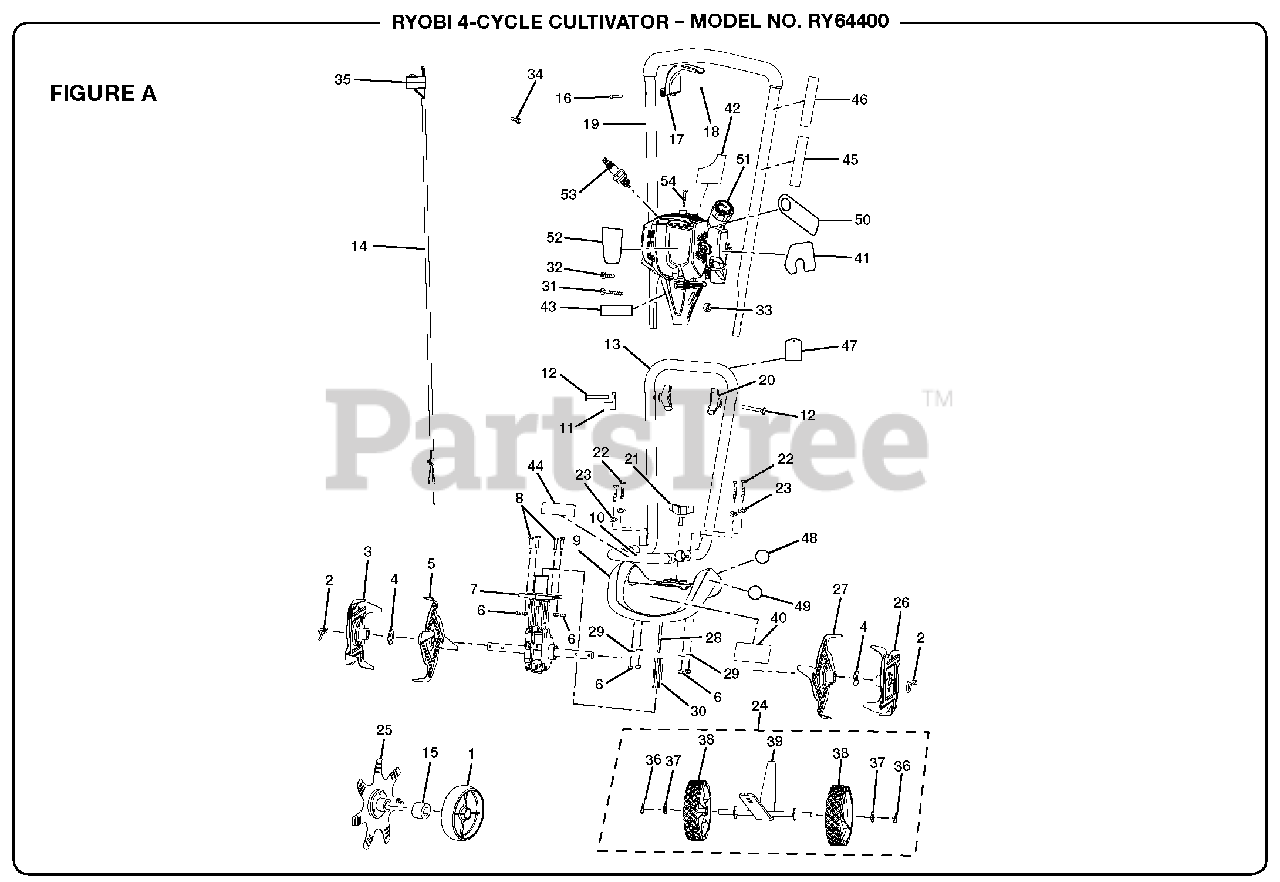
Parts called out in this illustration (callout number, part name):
1	Edger Wheel
2	Clevis Pin
3	Tine D, Outer Left
4	Felt Washer
5	Tine C, Inner Left
6	Lock Nut (1/4-20)
8	Bolt (1/4-20 x 1 in.)
9	Tine Shield Assembly
10	Front Handle
12	Bolt (M8 x 60 mm)
13	Lower Handle
14	Throttle Cable Assembly (Incl. Key No. 55)
18	Retaining Ring
19	Upper Handle Assembly
20	Knob (M8)
21	Knob (M8 x 25 mm)
22	Bolt (1/4-20 x 1-1/2 in.)
23	Curved, Washer
24	Wheel/Drag Stake Assembly (Incl. Key No. 36-39)
25	Edging Tine
26	Tine A, Outer Right
27	Tine B, Inner Right
28	Drive Shaft
31	Screw (M6 x 20 mm)
32	Screw (8-16 x 3/8 in., T.F.)
33	Hex Nut (M6)
34	Screw (8-16 x 1/2 in., T.F.)
36	Cotter Pin
38	Wheel Assembly (6 in. Dia.)
39	Frame Assembly
40	Ryobi Logo Label
41	Quick Start Label
42	Hot Surface Label
43	Combustion Warning Label
44	Front Handle Label
45	Cultivator Warning Label
46	Cultivator Icon Warning Label
47	Hang Tag (French/Spanish)
48	Foot Warning Label
49	Hand Warning Label
50	Oil Warning Hang Tag
51	Fuel Cap
52	Logo Label (4-Cycle)
53	Spark Plug (Champion RZ7C)
54	Screw (M5 x 20 mm)
